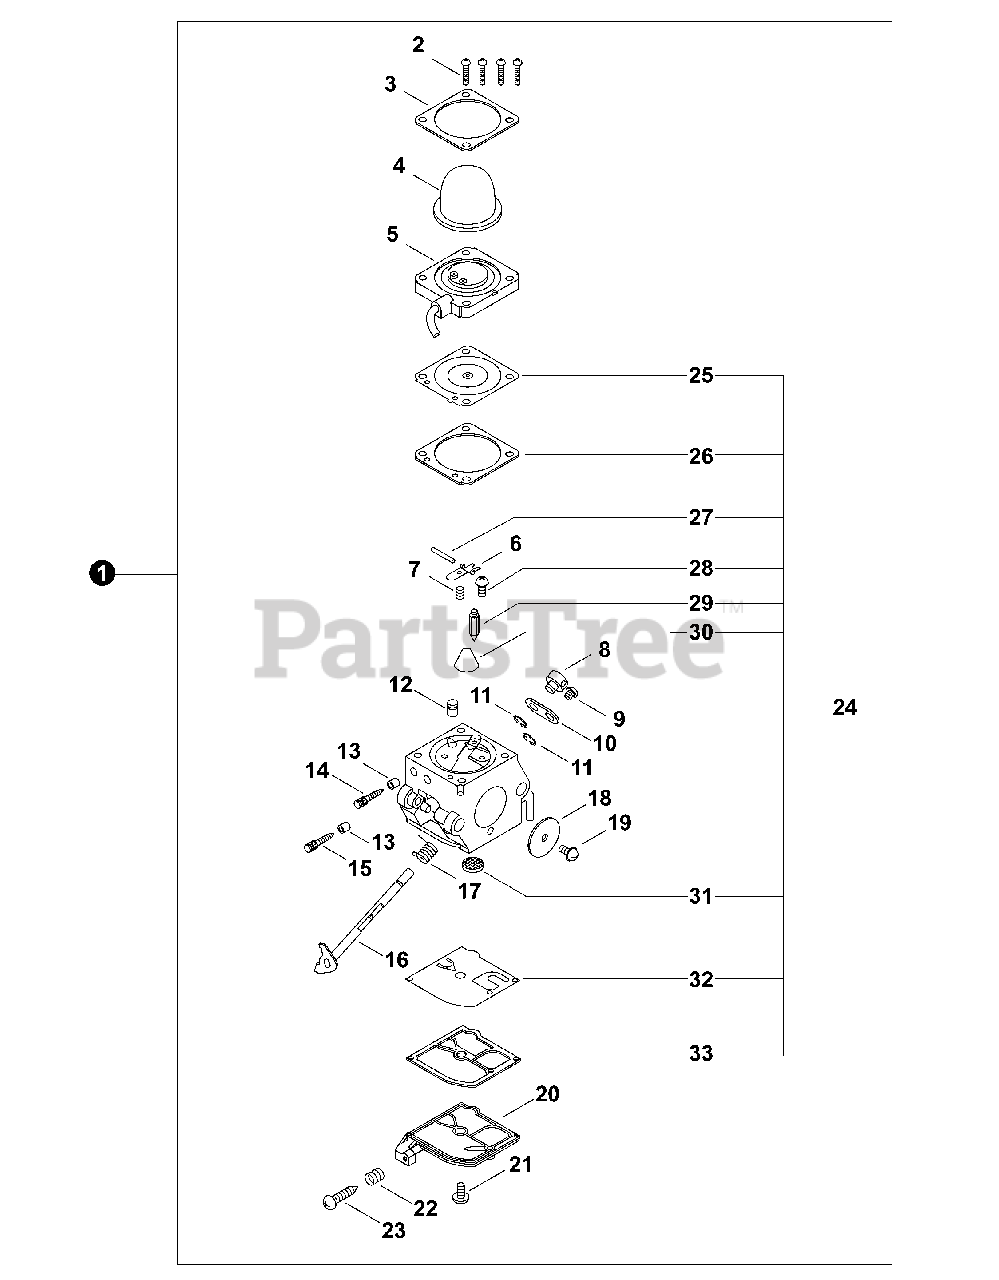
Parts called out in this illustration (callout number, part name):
1	CARBURETOR - C1Q-K73C
3	RETAINER, PURGE BULB
4	BULB, PURGE
5	BODY ASSY, PUMP
6	LEVER, METERING
10	LEVER, THROTTLE
12	NOZZLE, CHECK VALVE
13	RETAINER
14	NEEDLE, HIGH SPEED
15	NEEDLE, LOW SPEED
16	SHAFT ASSY, THROTTLE
18	VALVE, THROTTLE
20	COVER, PUMP
24	REPAIR KIT, CARBURETOR
25	DIAPHRAGM, METERING
26	GASKET, METERING DIAPHRAGM
27	PIN, METERING LEVER
29	VALVE, INLET NEEDLE
30	PLUG, WELCH
31	SCREEN, FUEL INLET
32	DIAPHRAGM, PUMP
33	GASKET, PUMP
